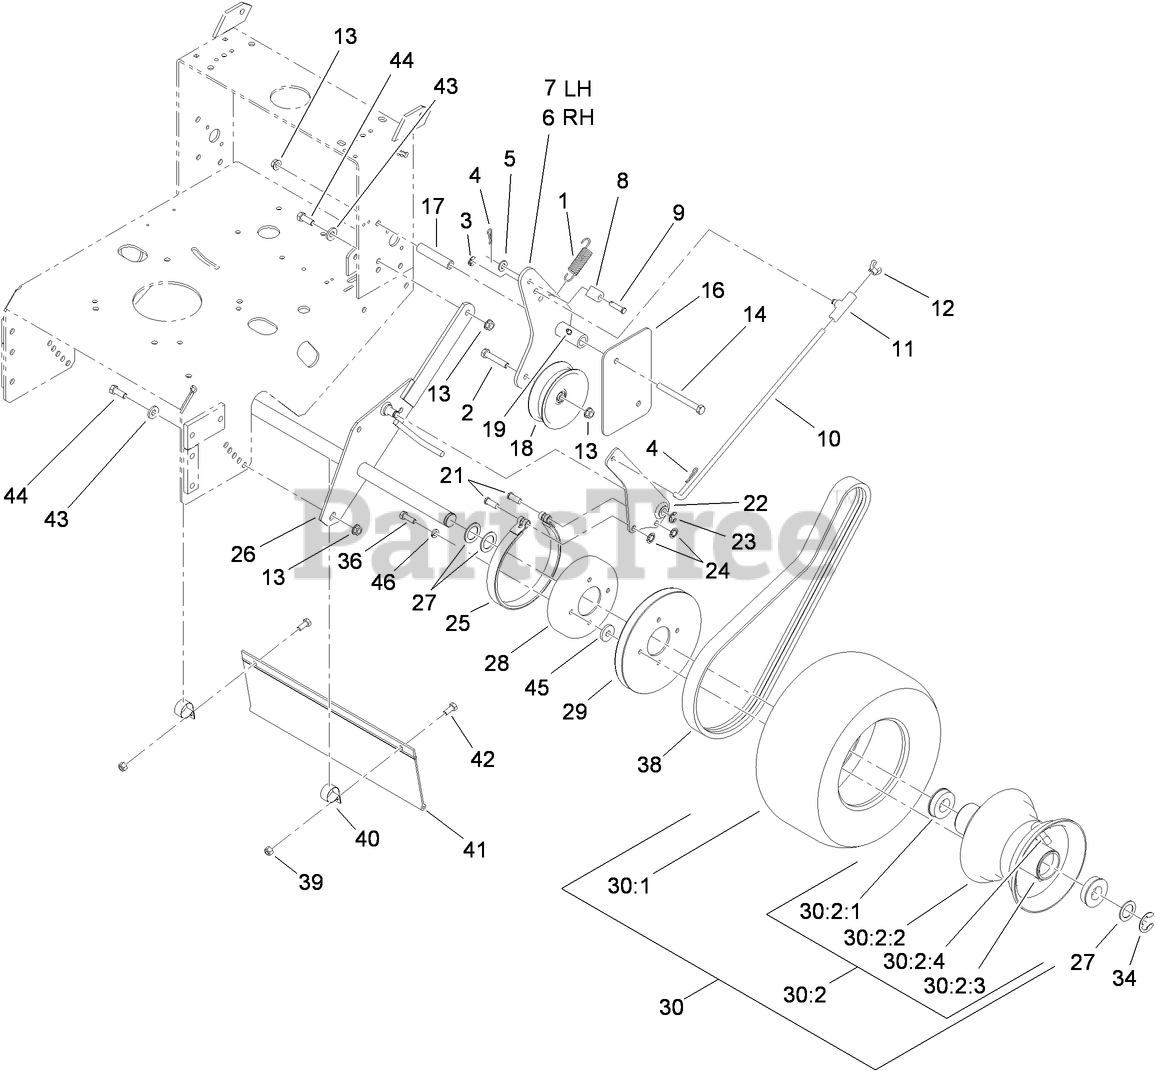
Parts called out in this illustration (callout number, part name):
1	SPRING-EXTENSION
2	SCREW-HH
3	RING-RETAINING
4	PIN-COTTER
5	WASHER-PLAIN
6	ARM-IDLER, RH
7	ARM-IDLER, LH
8	FITTING-ROD
9	PIN-CLEVIS
10	ROD-BRAKE
11	SWIVEL-BRAKE
12	WINGNUT-NYLOCK
13	NUT-HHF, WHIZ
14	SCREW-HH
16	SHIELD-WHEEL, DRIVE
17	SPACER-SHIELD
18	IDLER-DRIVE, WHEEL
19	FITTING-GREASE
21	PIN-CLEVIS
22	ARM-BRAKE
23	RING-RETAINING, EXTERNAL
24	NUT-PUSH
25	BAND-BRAKE
26	AXLE ASM
27	WASHER-SPACER
28	DRUM-BRAKE
29	SHEAVE-WHEEL, DRIVE
30	Wheel AND Tire ASM
30:2	WHEEL AND HUB ASM
30:2:1	BEARING-FLANGED
30:2:2	Rim ASM
30:2:3	Fitting-Grease
30:2:4	Valve Stem and Cap
34	RING-SNAP
36	SCREW-HH
38	BELT-DRIVE, WHEEL
39	NUT-LOCK, NI
40	CLAMP-R
41	SHIELD-TRAILING
42	SCREW-HH
43	WASHER-BELLEVILLE
44	SCREW-HH
45	WASHER
46	WASHER-LOCK
